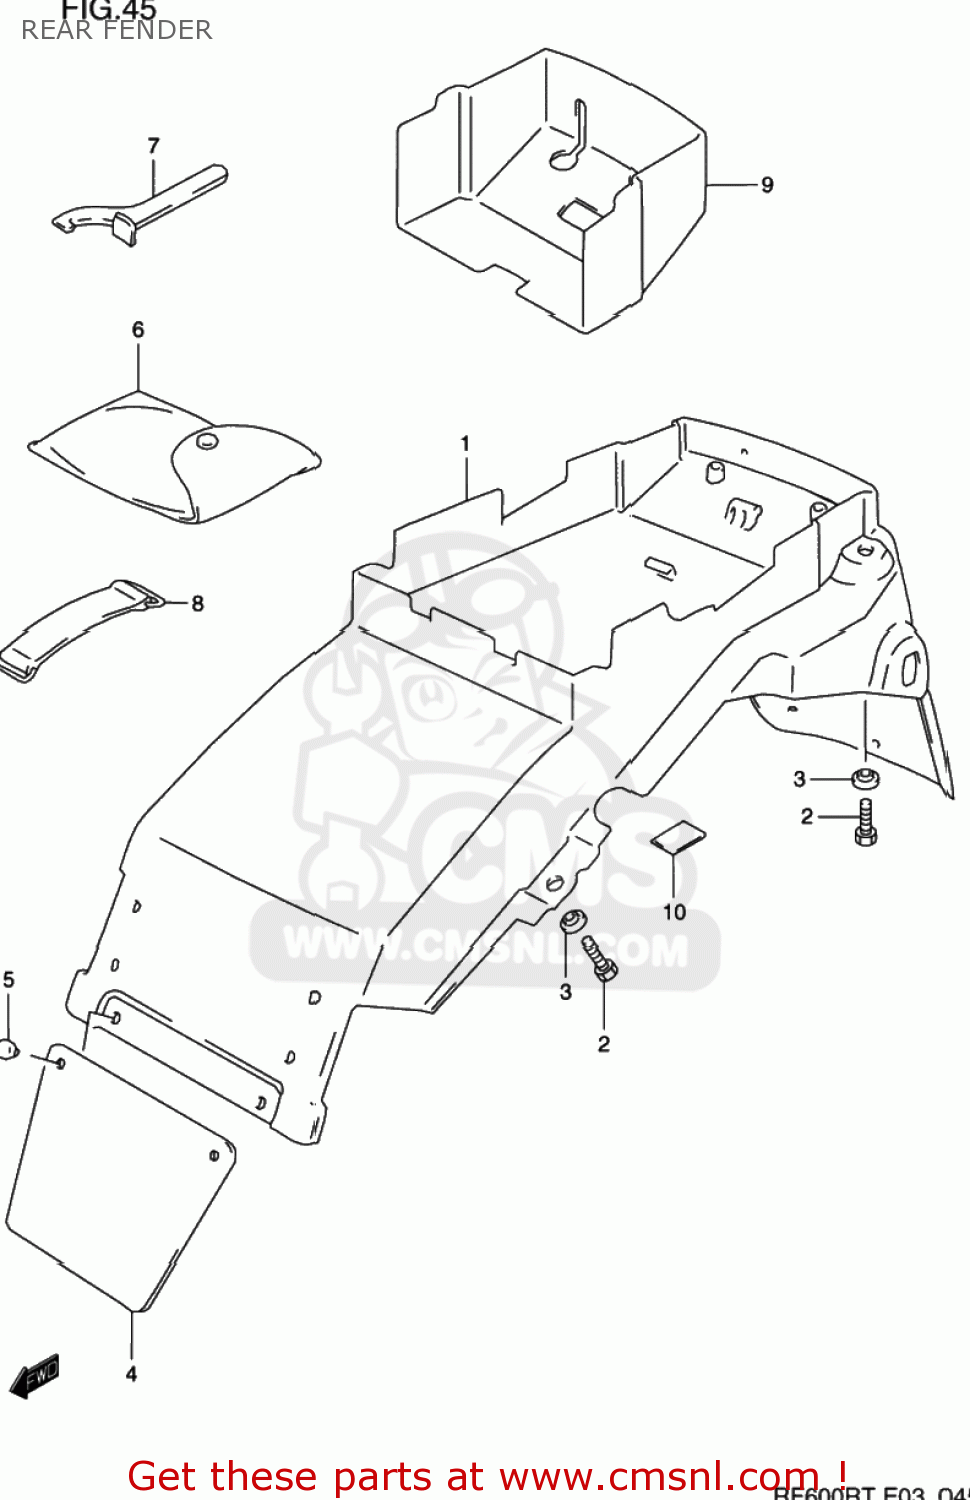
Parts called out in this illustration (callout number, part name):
1	FENDER,RR
2	BOLT
3	WASHER
4	GUARD,RR FENDER MUD
5	CLIP,MUDGUARD
6	TOOL ASSY
7	CLAMP
8	BAND
9	GUARD,RR FENDER
10	TAPE,RR FENDER
